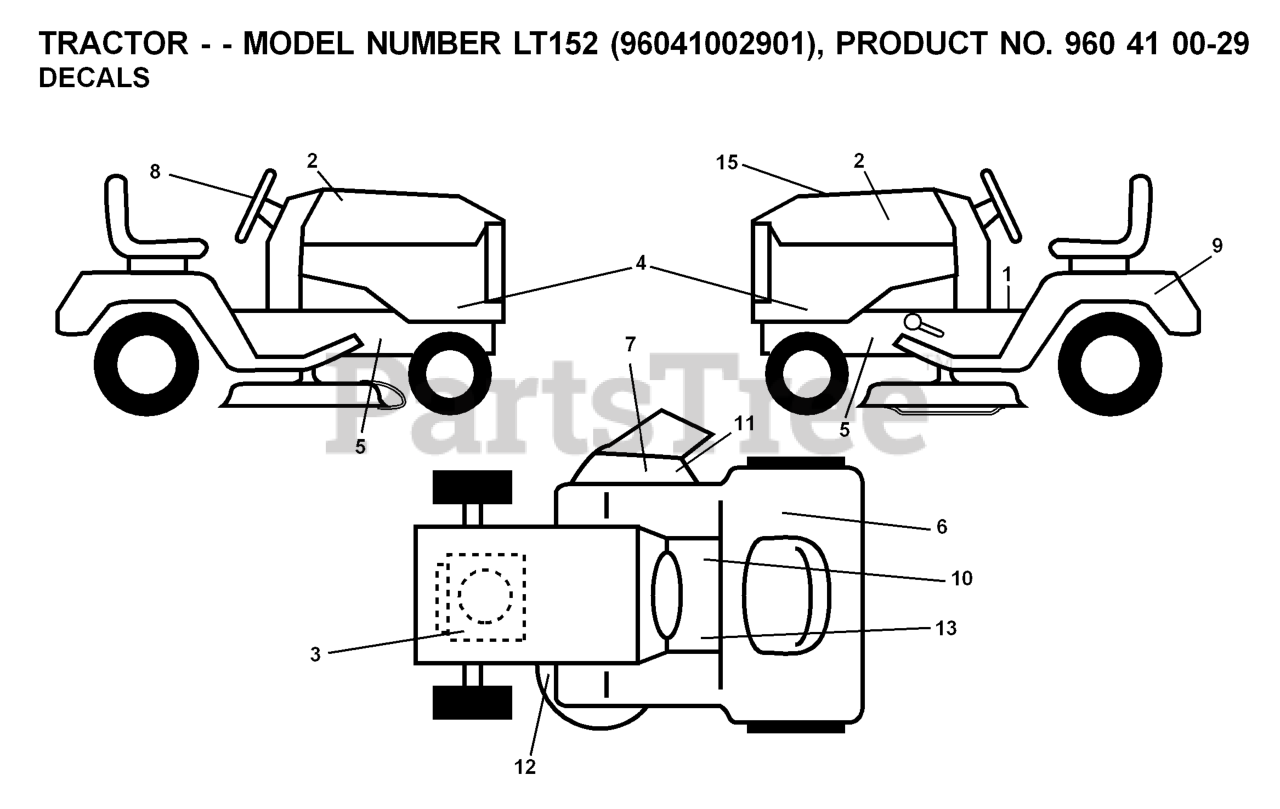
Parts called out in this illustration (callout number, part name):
1	LABEL
2	DECAL.HOOD.NAMELOGO.HUSQ
3	DECAL
6	Decal, Fender 100 DB/CE
7	DECAL.INTERNATIONL.CUTFINGER
8	DECAL.WHEEL.STRG.LGN.H
9	DECAL BTRY SYMBOLS
10	DECAL PARK BRAKE
11	DECAL, DEFLECT WARNING
12	DECAL V BELT SCHEMATIC
13	DECAL
